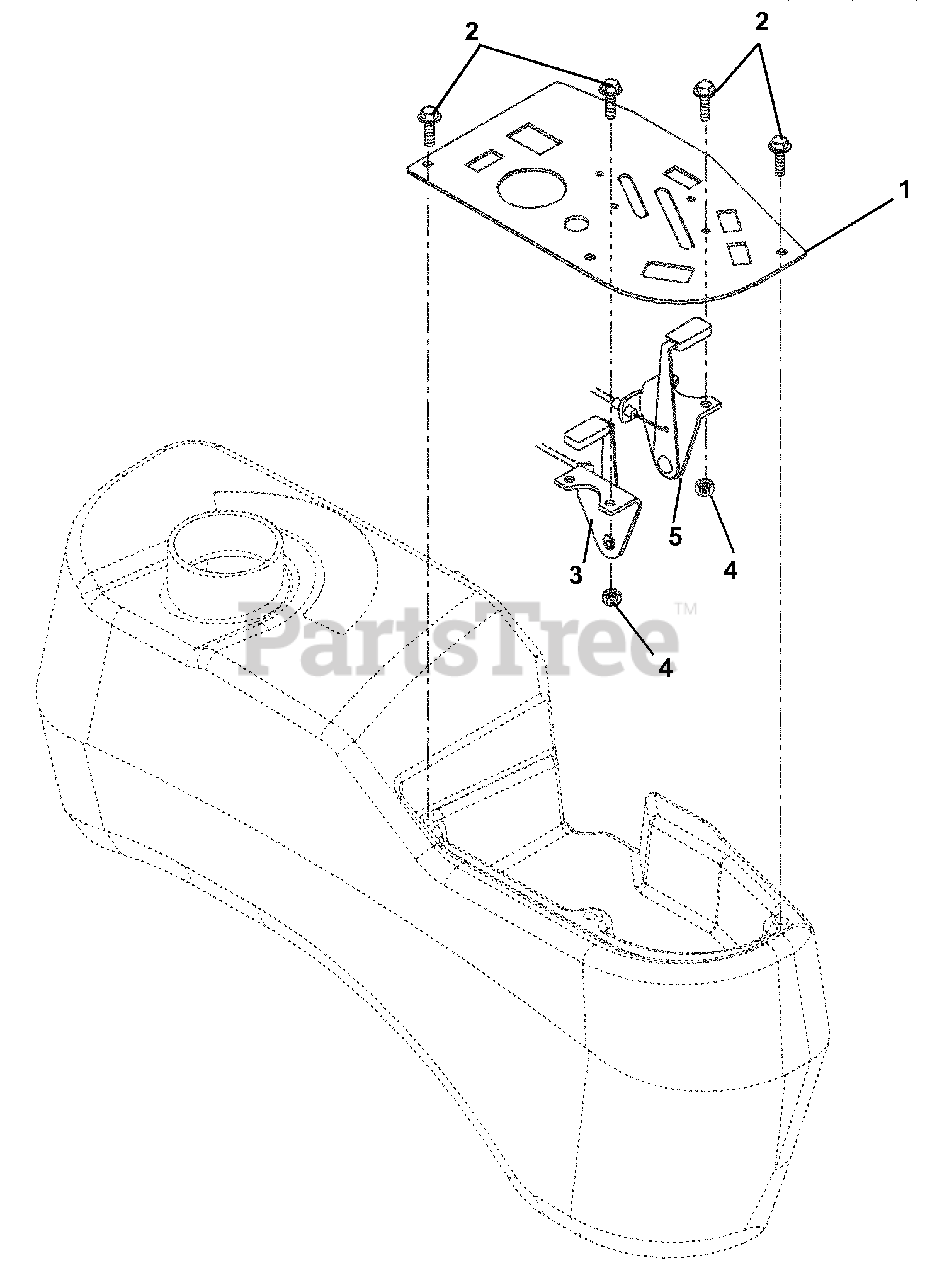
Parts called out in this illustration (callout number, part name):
1	Panel-Control
2	Screw-Machine 10-24 x .50 Hex Washer Head
3	Throttle, Control
4	Nut-Locking-Nylon 10-24 With Insert
5	Choke Control
